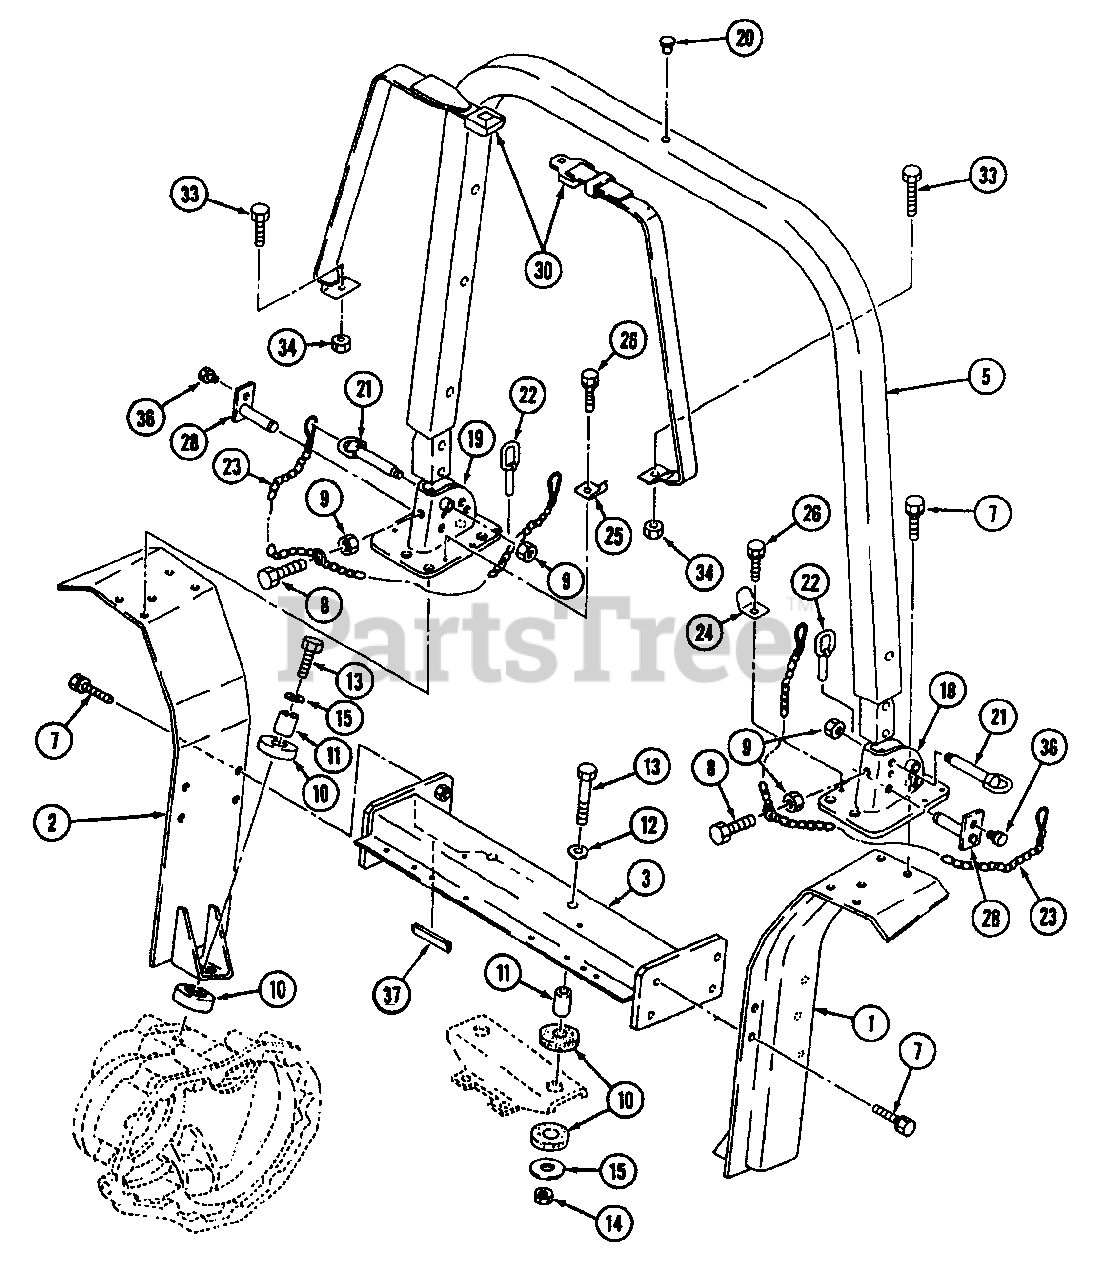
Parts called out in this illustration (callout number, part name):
2	Frame R.H.
10	Rubber, Cushion
24	Hook, Seat Belt L.H.
25	Hook, Seat Belt R.H.
30	Seat Belt Ass'y.
